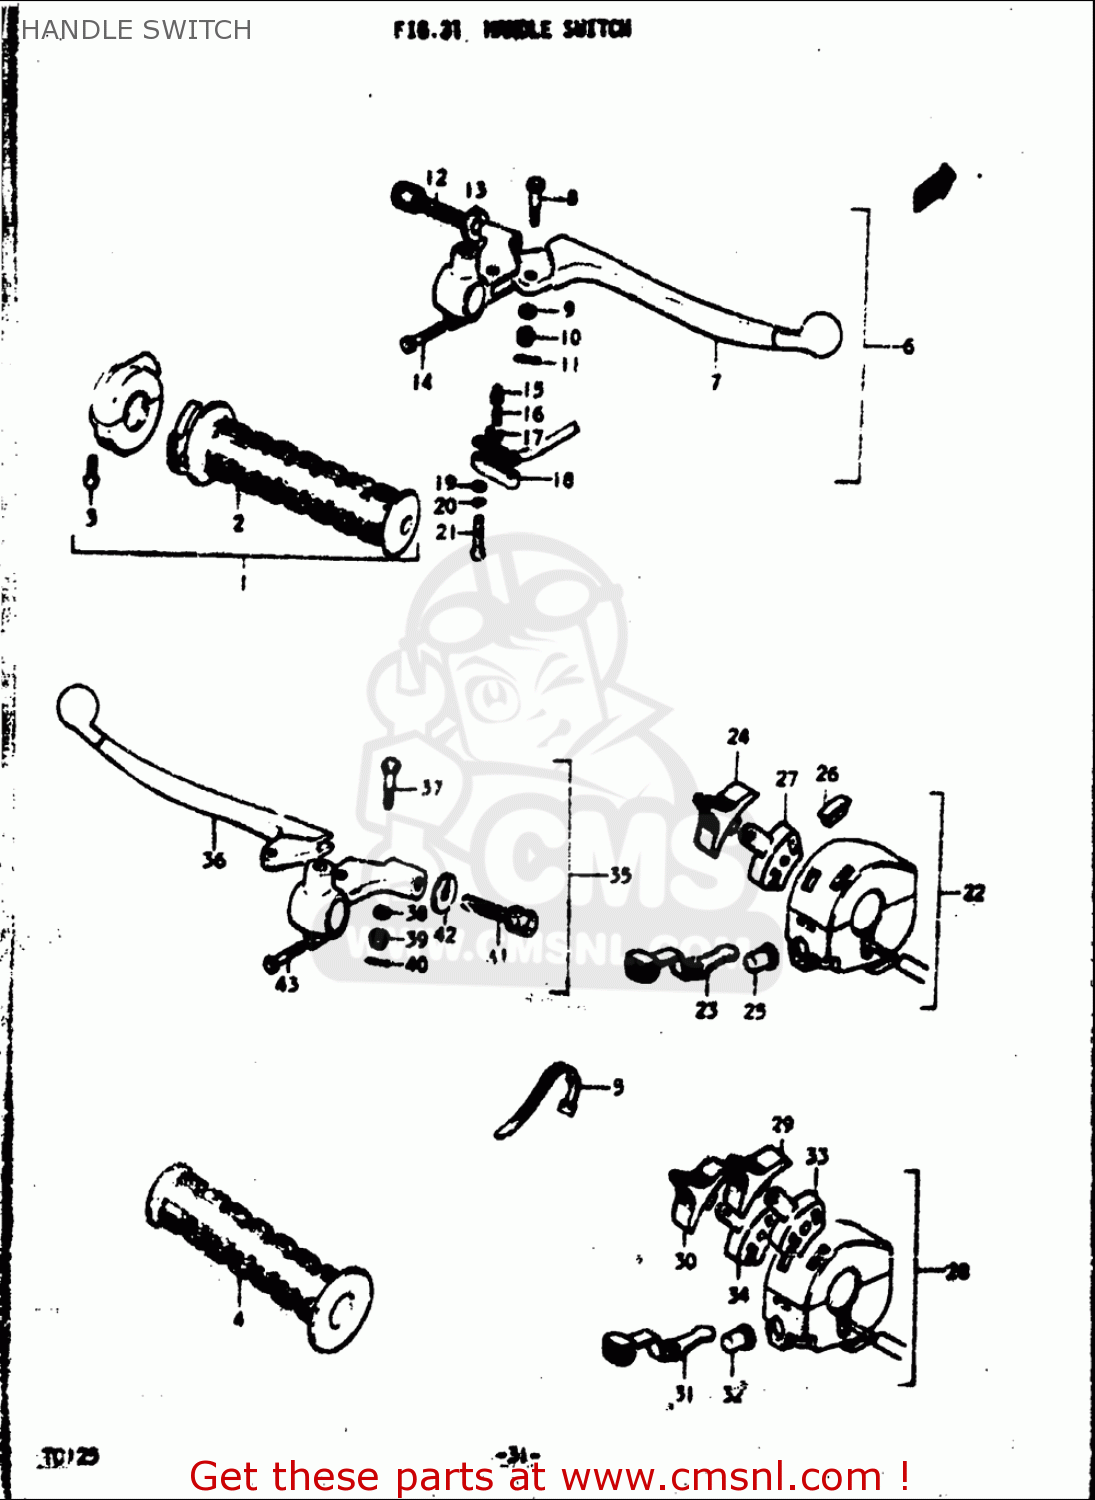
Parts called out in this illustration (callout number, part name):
1	GRIP ASSY,THROTTLE
2	GRIP,THROTTLE
3	SCREW
4	GRIP
5	CLAMP(L:120)
6	BRAKE LEVER & SWITCH ASSY
7	LEVER,BRAKE
8	BOLT,LEVER PIVOT
9	WASHER,LOCK
10	NUT,LEVER FITTNG
11	PIN 16X20
12	ADJUSTER,CABLE
13	NUT,CABLE ADJUSTER
14	BOLT
15	CONTACT,SWITCH
16	CONTACT,SWITCH
17	CONTACT,SWITCH
18	COVER,FR BK TERMINAL BASE
19	WASHER
20	WASHER,LOCK
21	SCREW
23	KNOB,HANDLE SWITCH
25	BUTTON, HORN
31	KNOB,HANDLE SWITCH
32	BUTTON, HORN
34	SLIDING BLOCK, DIMMER SWITCH
35	LEVER ASSEMBLY,CLUTCH
36	LEVER,CLUTCH
37	BOLT,LEVER PIVOT
38	WASHER,LOCK
39	NUT,LEVER FITTNG
40	PIN 16X20
41	ADJUSTER,CABLE
42	NUT,CABLE ADJUSTER
43	BOLT
